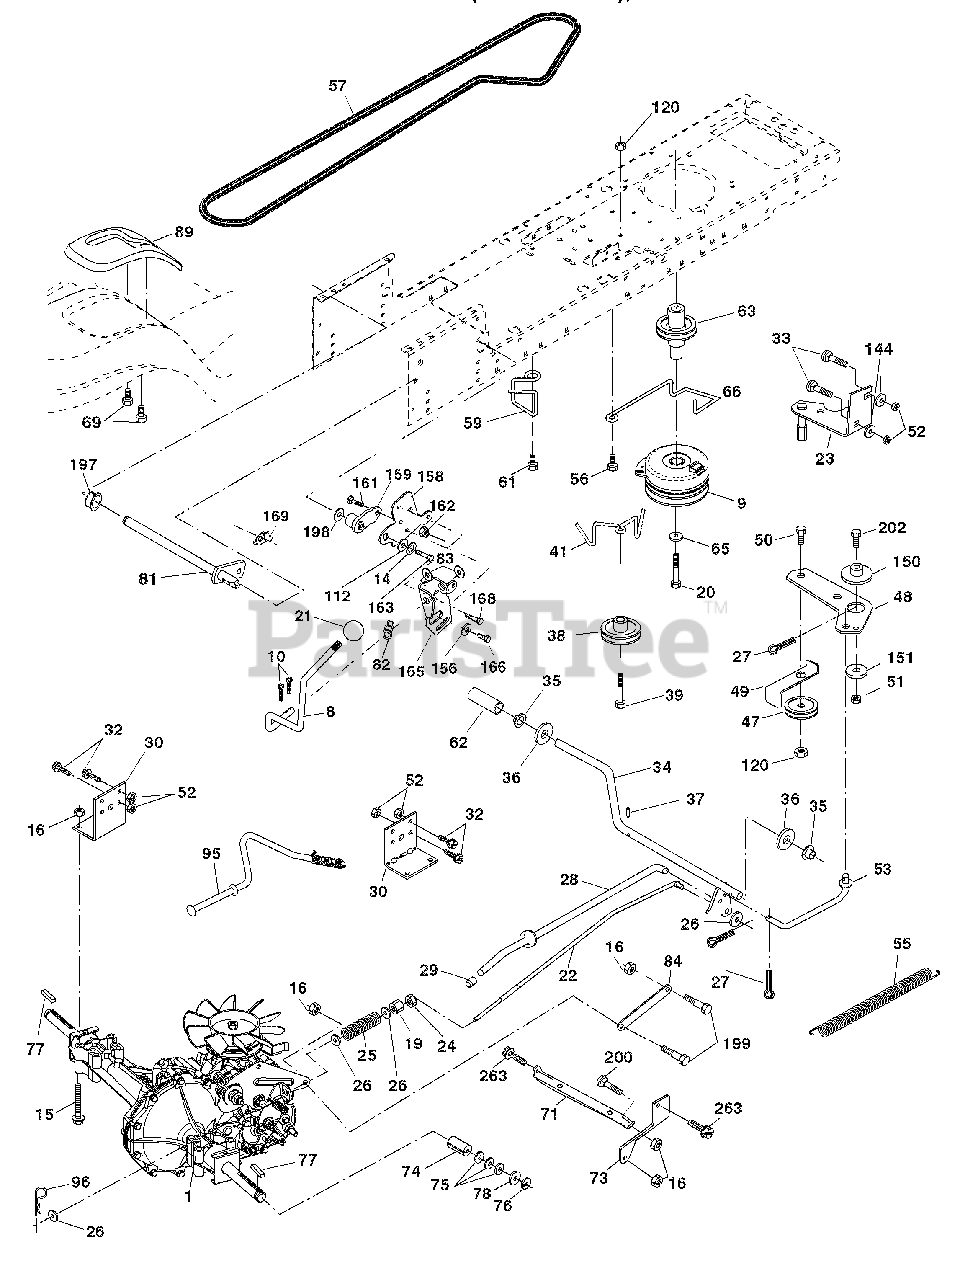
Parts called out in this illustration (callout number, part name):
9	Clutch Elect. EVX
10	Pin Cotter 1/8 x 1 CAD
14	Washer Lock Hvy Helical
15	Bolt, Hex FLGHD 5/16-18 Gr. 5
16	Nut Lock Hex w/Ins 5/16-18 unc
19	Nut Lock Hex w/Wsh 3/8-16 unc
20	Bolt Hex 7/16-20 x 4-1/4 5 Ga. 1.38
22	Rod, Brake Hydro
23	Bracket Anti Rotation
24	Nut
25	Spring, Brake Rod
26	Washer
27	Pin Cotter 1/8 x 3/4 CAD.
28	Rod, Parking Brake
29	Cap, Parking Brake
30	Bracket, Transaxle
32	Bolt Hex Hd 5/16-18 unc x 3/4
33	Bolt RDHD SQNK 5/16-18 unc x 3/4
34	Shaft, Foot Pedal
35	Bearing, Nylon
36	Washer
37	Pin, Roll
38	Pulley, Composite
39	Bolt Rdhd 3/8-16 unc x 2-3/4 Gr. 5
41	Keeper, Belt Idler
47	Pulley, Idler, V-Groove
48	Bellcrank Clutch Grnd Drv STL
49	Retainer, Belt
50	Bolt Carr Sh 3/8-16 x 1-1/2 Gr. 5
51	Nut Crownlock 3/8-16 unc
52	Nut Crownlock 5/16-18
53	Link, Clutch
55	Spring, Return, Clutch
56	Screw 3/8-16 x 1-1/4
57	V-Belt, Ground Drive
59	Keeper, Center Span
61	Screw 3/8-16 x .875
62	Cover, Pedal
63	Pulley, Engine
65	Washer
66	Keeper Belt Engine
69	Screw Hex Wsh Hi-Lo 1/4 x 1/2 unc
71	Strap Torque LH Hydro
73	Strap Torque RH Hydro
74	Spacer, Axle
75	Washer 25/32 x 1-1/4 x 16 Ga.
77	Key, Square
78	Washer 25/32 x 1-5/8 x 16 Ga.
81	Shaft Asm. Cross Hydro
82	Spring Torsion T/A
83	Washer 17/32 x 3/4 x 16 Ga.
84	Link Transaxle
89	Console, Shift
95	Control Asm Bypass Hydro
96	Retainer Spring 1" Zinc/Cad
112	Washer 9/32 x 3/4 x 10 Ga.
120	Nut Lock Flg 3/8-16 unc
144	Washer 11/32 x 5/8 x 16 Ga.
150	Spacer Retainer
151	Washer 13/32 x 2 x 10 Ga.
156	Washer Srrted 5/16 ID x 1.125
158	Bracket Shift Mount
159	Hub Shift
161	Bolt Rdhd Sqnk 1/4-20 x 3/4 Gr. 5
162	Nut Crownlock 1/4-20 unc
163	Bolt Hex Fin 1/4-20 unc x 1 Gr. 5
165	Bracket Pivot Lever
166	Screw 5/16-18 x 5/8
168	Bolt Shoulder 5/16-18 x .561
169	Plate Fastening Lt
197	Nyliner Snap-In 5/8" ID
198	Washer Nylon 7/8 ID x .105
199	Bolt Shoulder 5/16-18 unc
200	Bolt Rdhd Sqnk 5/16-18 unc x 1
202	Bolt Carr Sh 3/8-16 x 1-3/4 Gr. 5
263	Thdrol Screw 3/8-16 x 3/4
